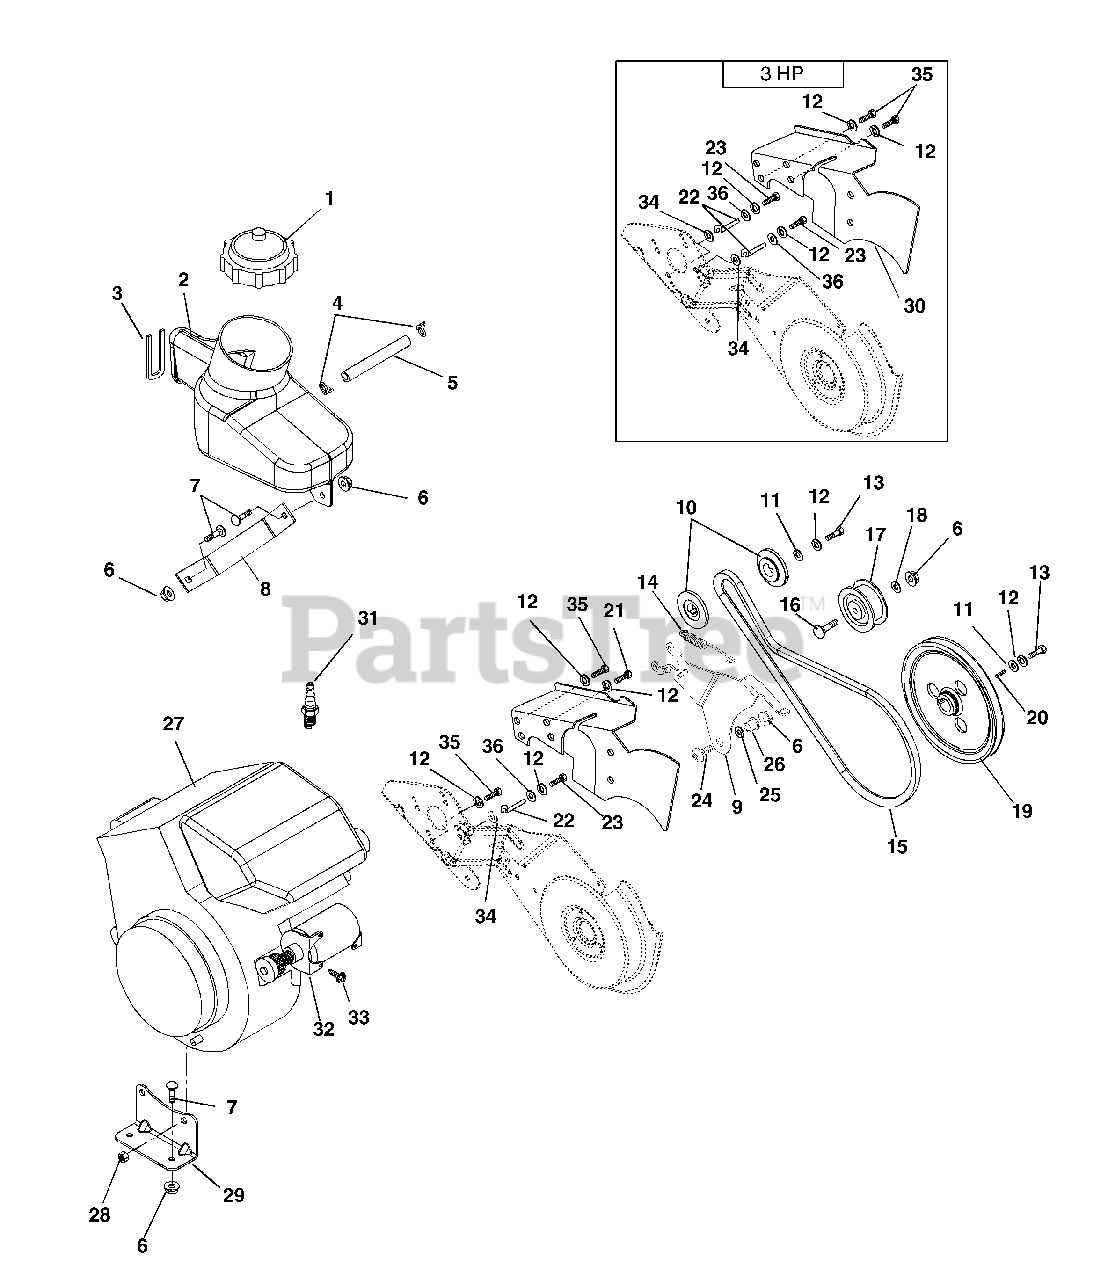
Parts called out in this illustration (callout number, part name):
1	CAP-FUEL
2	KIT, 938 FUEL TANK
3	TAPE FOAM,NEOPRENE
4	CLAMP-HOSE WIR.490/.510X.092#8
5	GAS LINE 1/4" I.D. X 9.5
5	GAS LINE HOSE 1/4 X 11"
6	NUT-LK-FLG .250-20 PL BLK
7	@BLT-RDHDSQNK .25-20X.75 G5YZ
8	BRKT-FUEL TANK MTG
9	ARM-IDLER
10	PLY-DRIVE 3LX 1.80 DIA
10	PLY-DRIVE 3LX 1.52 DIA
11	@WSHR-FL-STL.38X.875X.083 YWZC
12	WSHR-LK .312X.097 HVY YWZC
13	BLT-HEX .31-24X.75 YWZC GR5
14	SPRING, EXTENSION
15	V-BELT, 3L-RAW EDGE
16	@BLT-RDHDSQNK .25-20X1.25 G5YZ
17	IDLER-FLAT 1.75 X .27 DAYCO
18	WSHR-FL-STL .281X1.000X.063
19	PLY-V 5.50X.671 W/KEY "A"
20	KEY-SQ .188X.75X.188
21	SCR-CAP .31-18X.75 S/HD
22	FINGER-BELT
23	@BLT-HEX .31-18X1.00 GR5 YWZC
24	SCR-MCH .25-20X.75 TXTR YWZC
25	WSHR-FL-STL .505X.875X.024 YWZ
26	BSHG-FLG .265X.437X.250X.750
27	ENGINE, TH139SA 5HP 2CY TEC
27	ENGINE-HSK600 3HP 2-CY (EPA-C)
27	ENGINE, TH139SP 7HP 2CYL TEC.
28	@NUT-LK-CTR .31-18 YWZC
29	BRKT-ENGINE MTG
30	BAFFLE-BELT PROTECTIVE
31	PLUG, SPARK
32	MOTOR-STARTING
33	SCR-HFWH-TX-SEMS .25-20X.49 TE
34	@WSHR-LK-EXT.326X.599X.031YWZC
35	@BLT-HEX .31-18X.75 GR5 YWZC
36	@WSHR-FL-STL.344X.688X.065YWZC
